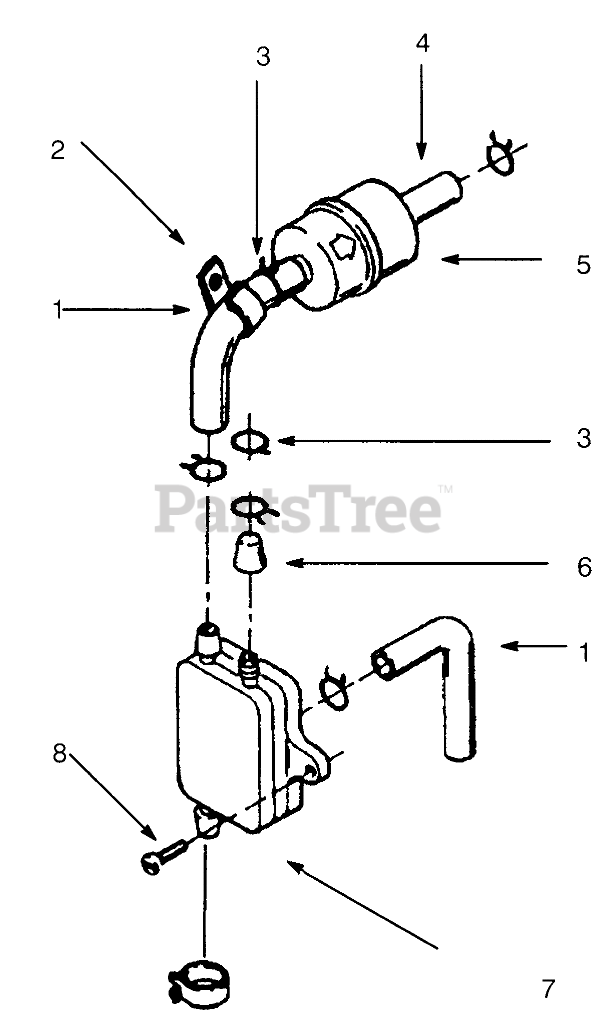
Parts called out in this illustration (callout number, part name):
1	Hose
2	Clip
3	CLAMP-HOSE
4	FUEL HOSE
5	FILTER-FUEL
6	CAP-FUEL OUTLET
7	PUMP-FUEL
8	SCREW-TAPPING PAN HD
